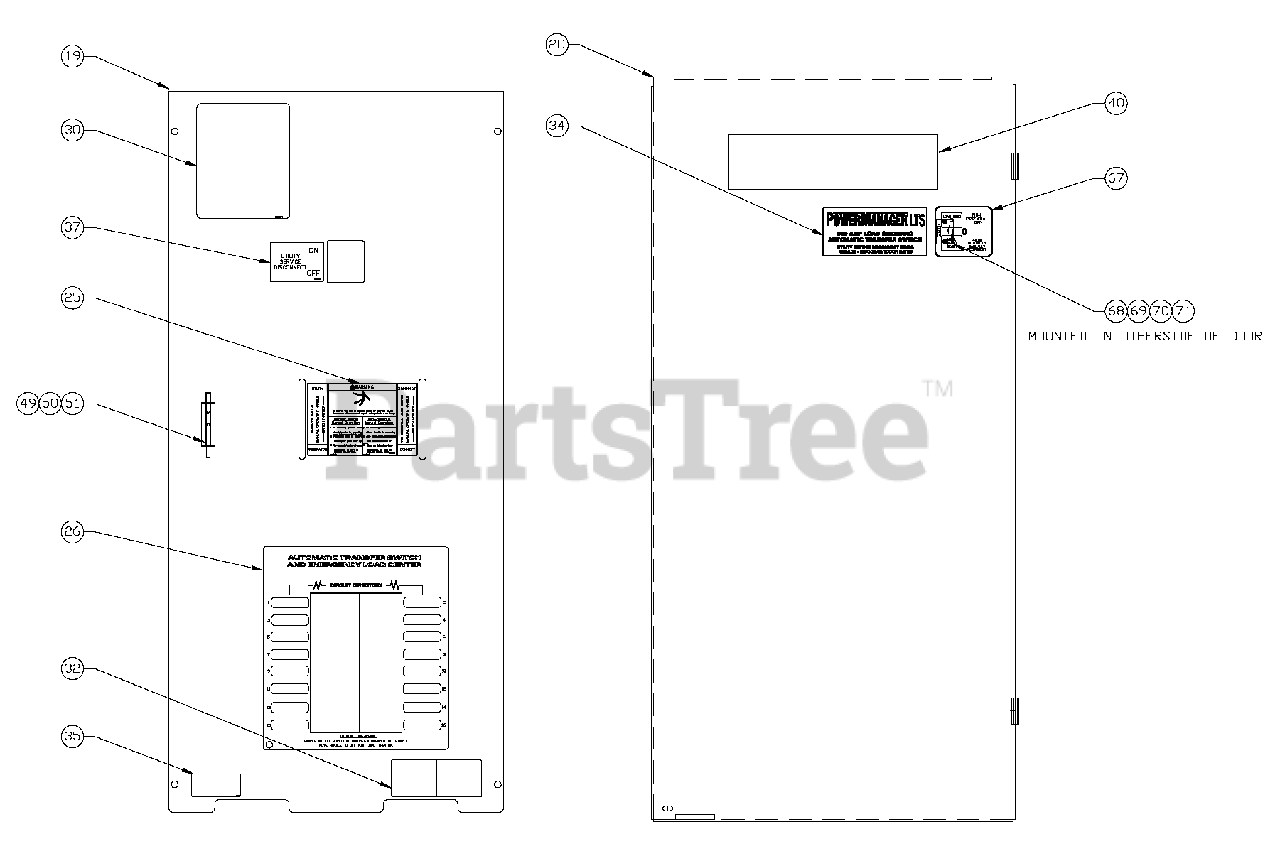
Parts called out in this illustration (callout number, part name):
19	INSIDE COVER LOAD SHED SIEMENS
20	COVER LOAD SHED ENCLOSURE
25	DECAL, WARN MANUAL OPER HANDLE
26	DECAL, FRT GTS LD CTR 16 CIR GRY
30	DECAL, TEST SEQUENCE
32	DECAL, TERMINAL SHOCK HZD BI
34	DECAL, POWERMANAGER LTS
35	DECAL, LIVE CIRCUIT ENG/FRN/SPN
37	DECAL, UTILITY SERVICE DISCONNECT
39	DECAL, NON-ESSENTIAL LOAD CONN
40	DECAL, SIEMENS 3.2" X 11.8"
49	BRACKET, ARM EXTENDER
50	RIVET POP .156 X .362 AL
51	ARM EXTENDER PIN
67	KEYPAD, LOAD SHED
68	ASSY PCB INTFC LOAD SHED KEYPD
69	NUT HEX LOCK M4-0.7 SS NYL INS
70	SPACER M4/#8 X 5/16 X 1/4 NYL
71	CABLE, KEYPAD INTERFACE
